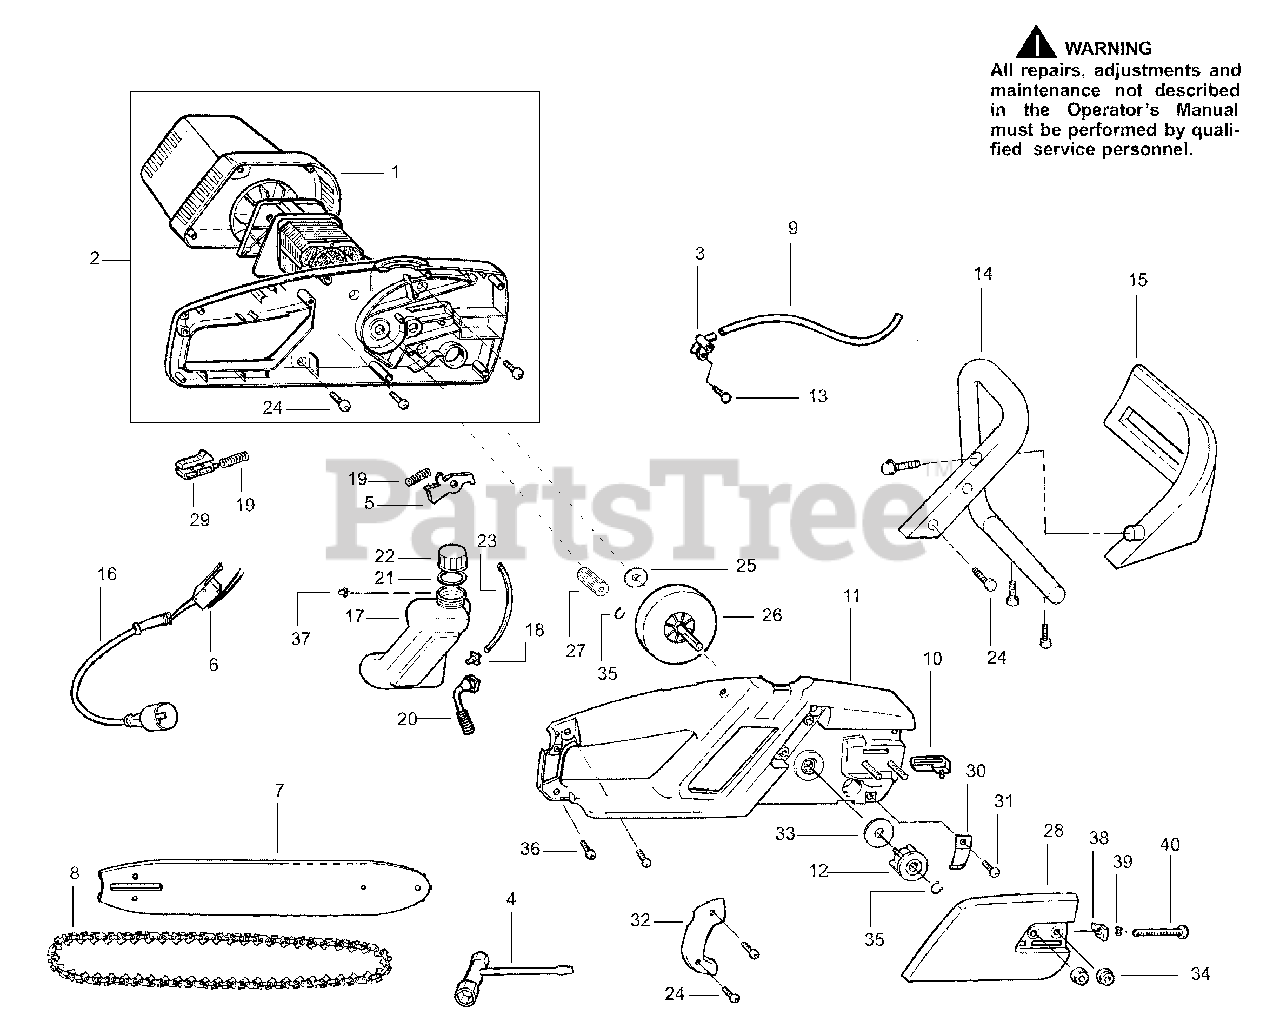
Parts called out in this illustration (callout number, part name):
1	Motor Cover
2	Housing/Motor Ass'y.
3	Oil Pump Ass'y.
4	Bar Wrench
6	Switch-Momentary
8	Chain-16"
9	Outlet Line
10	Insert Bar Pad
11	Housing Cover
12	Sprocket (3/8 Pitch)
14	Front Handle
15	Handguard
16	Cord Set
17	Oil Tank Ass'y.
18	Oil Pickup Fitting
19	Spring-Trigger
20	Oil Pickup Ass'y.
21	O-Ring (Oil Cap)
22	Oil Cap
23	Inlet Line
25	Washer-Thrust
26	Gear Drive
28	Bar Clamp
29	Lockout Button
30	Chain Catcher
32	Cover Access
33	Washer-Sprocket
34	Nut-Bar Mounting
35	Ring-Retainer
37	Check Valve (Duckbill)
38	Pin-Bar Adjust
39	Retainer-Bar Ajdust
40	Screw-Bar Adjust
